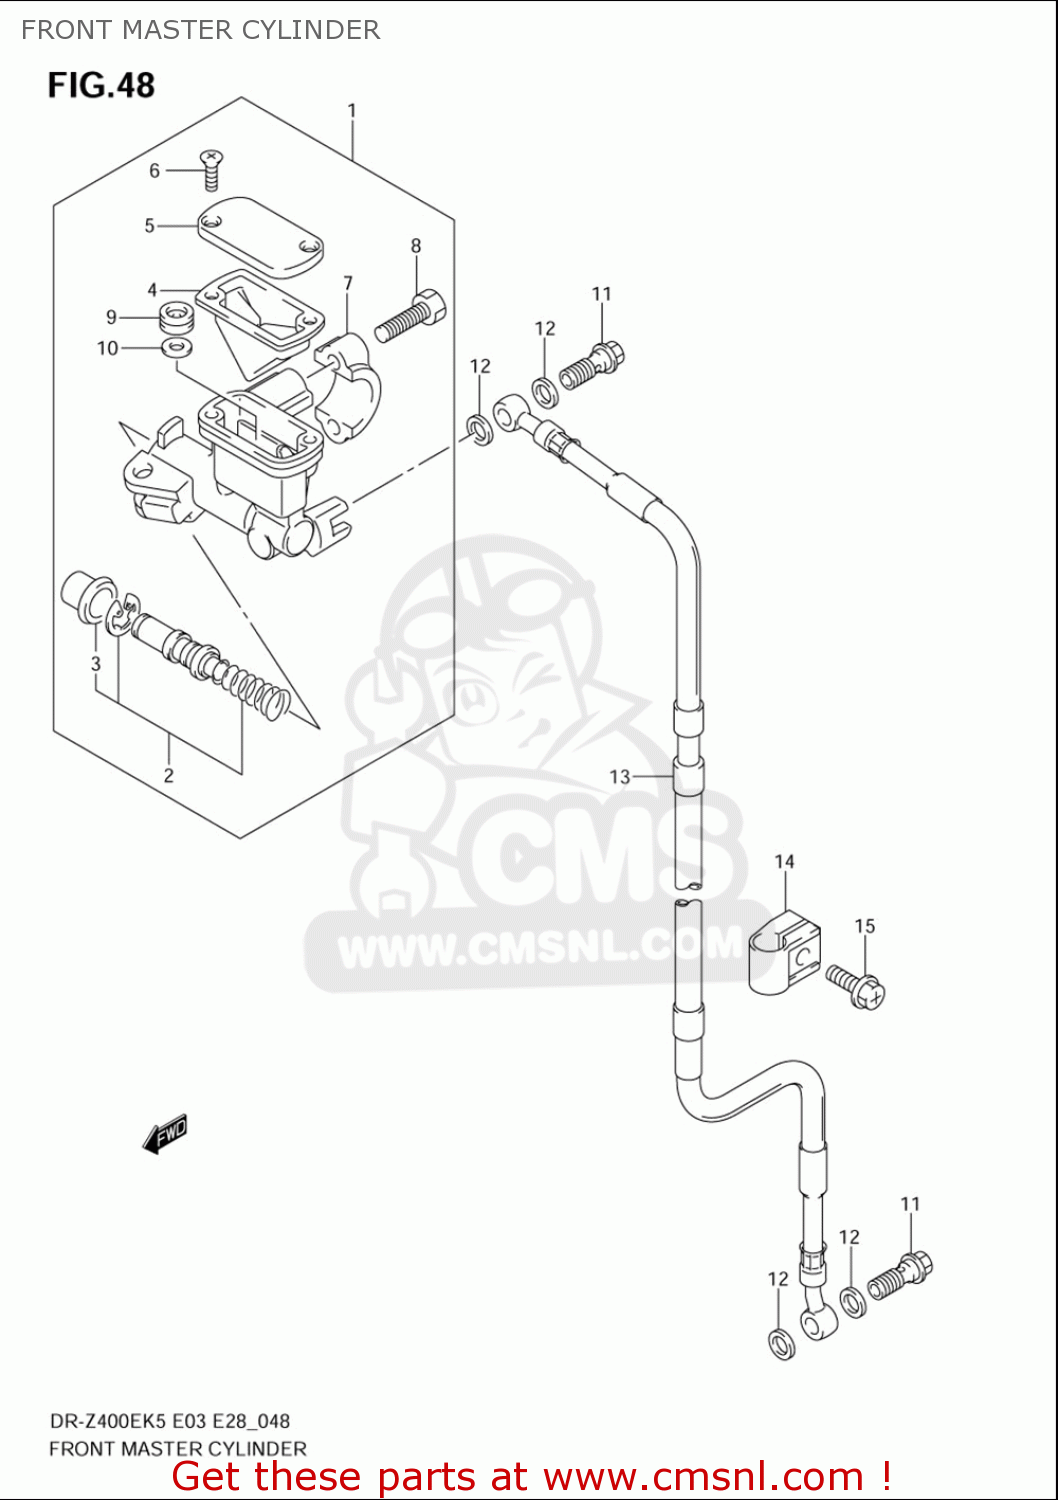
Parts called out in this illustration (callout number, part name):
1	CYLINDER ASSY,FR MASTER
2	PISTON & CUP SET
3	BOOT
4	DIAPHRAGM
5	CAP
6	SCREW
7	HOLDER
8	BOLT
9	SEPARATOR
10	RING
11	BOLT UNION
12	WASHER(10X15X1.5)
13	HOSE COMP,FRONT BRAKE
14	CLAMP,FR BRAKE
15	SCREW
